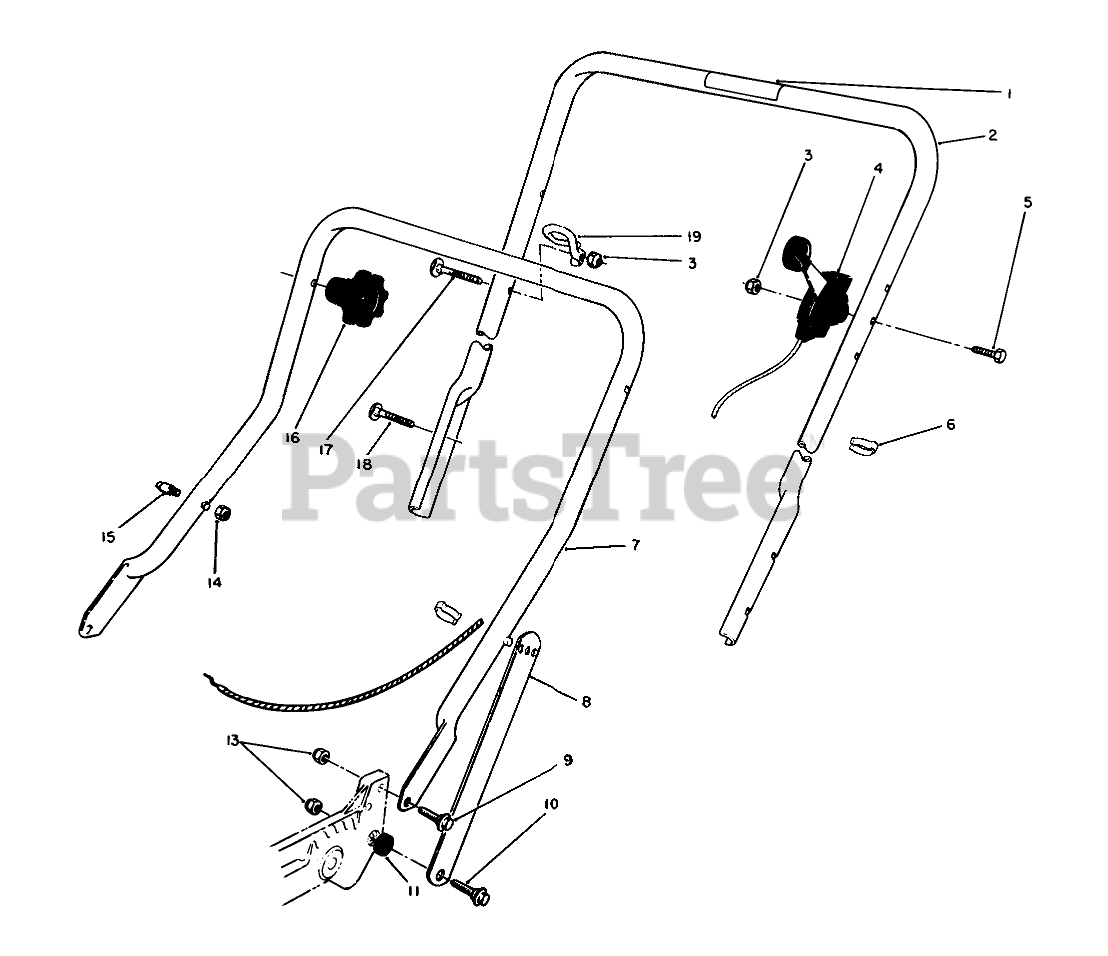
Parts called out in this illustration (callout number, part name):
1	Decal-Danger
2	Handle-Upper (Incl. Ref. #1)
3	NUT-LOCK, NI
4	THROTTLE CONTROL
5	SCREW-HANDLE
6	BOWDEN CLIP
7	LOWER HANDLE ASM
8	Handle Latch
9	SCREW-SHOULDER
10	SCREW-SHOULDER
11	SPACER
13	NUT-LOCK, NI
14	NUT-LOCK, NI
15	HANDLE PIN
17	HANDLE SCREW
18	5/16-18 X 2 HNDLE SCREW
19	Guide
